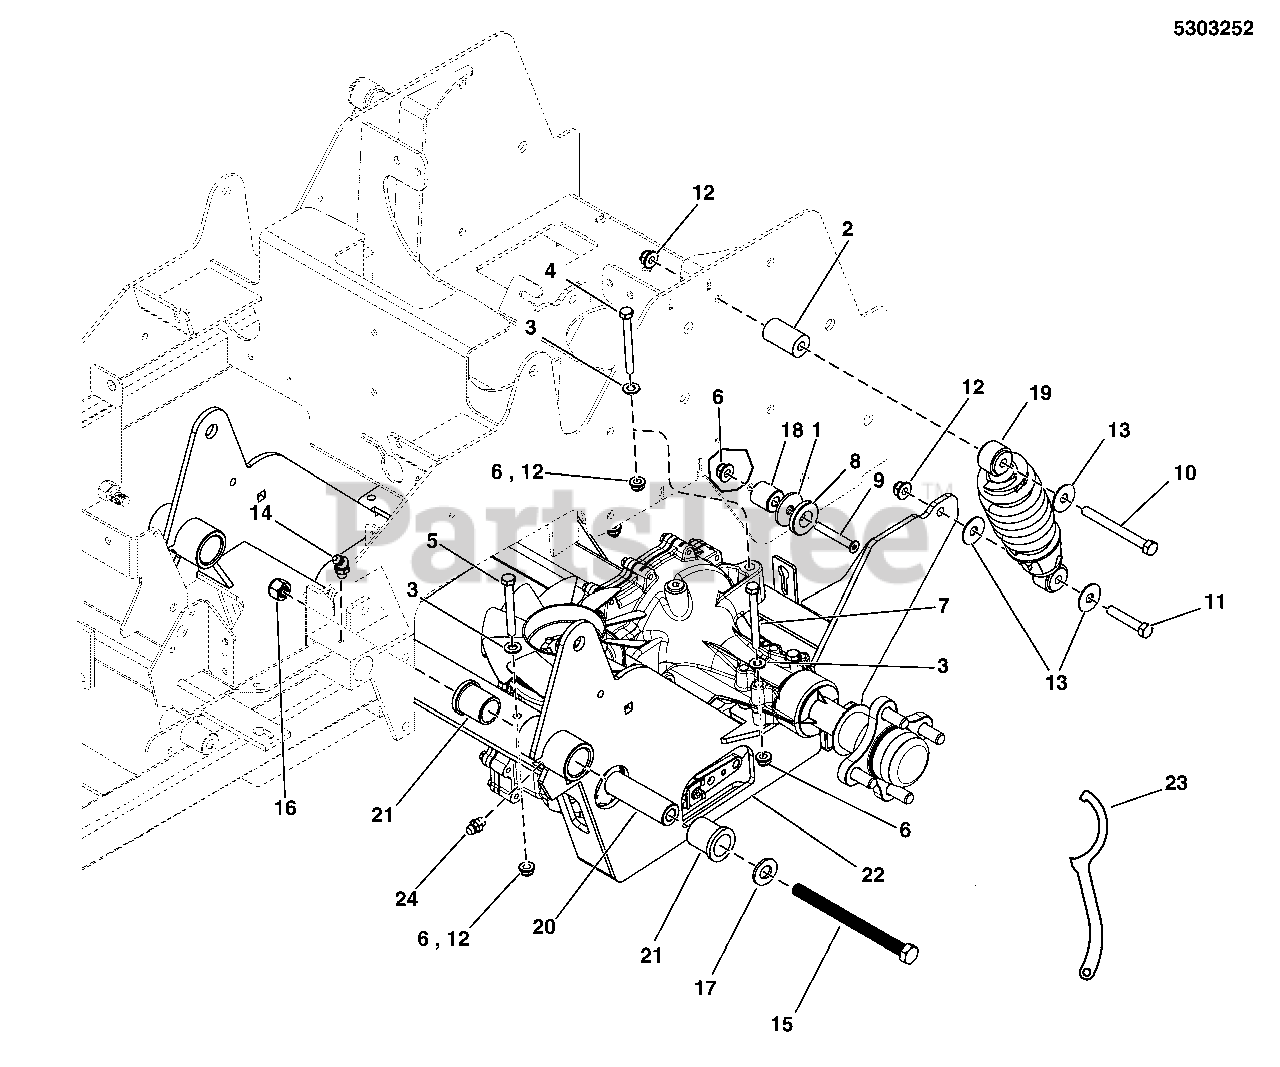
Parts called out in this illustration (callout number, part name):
1	WASHER, .390 X 1.50 X .109, YZ
2	SPACER, .390 X 1.00 X 1.00, CZ
3	WASHER, 5/16 SAE
3	WASHER, 3/8 SAE
4	BOLT, 5/16-18 X 2-1/2 GD5 YZ
4	BOLT, 3/8-16 X 2-1/2 GD5
5	BOLT, 5/16-18 X 2-3/4, GD 5, YZ
5	BOLT, 3/8-16 X 2-3/4 GD5
6	NUT, 5/16-18 HEX NYLOCK FLANGE
7	BOLT, 5/16-18 X 3 GD5 YZ
8	SPACER, .34 X 1.54 X .25 - UHMW
9	SCREW, 5/16-18X1.5
10	BOLT, 3/8-16 X 3 GD5 CZ
11	BOLT, 3/8-16 X 2 GD5 YZ
12	NUT, 3/8-16 HEX NYLOCK FLANGE
13	WASHER-3/8 FENDER
14	GREASE FITTING, 45 DEGREE
15	BOLT, 1/2-13 X 6-1/2 GD8, YZ
16	NUT, 1/2-13 HEX NYLON LOCK
17	WASHER, 1/2 SAE
18	SPACER, .39 X 1.00 X .50, CZ
19	SHOCK ABSORBER, IS600
20	SPACER, .52 X 1.00 X 3.42
21	BUSHING, FLANGE
22	WELD, SUSPENSION CRADLE, IS600 - ORG
23	WRENCH, SPANNER, CZ
24	GREASE FITTING, 1/4-28 STRAIGHT
